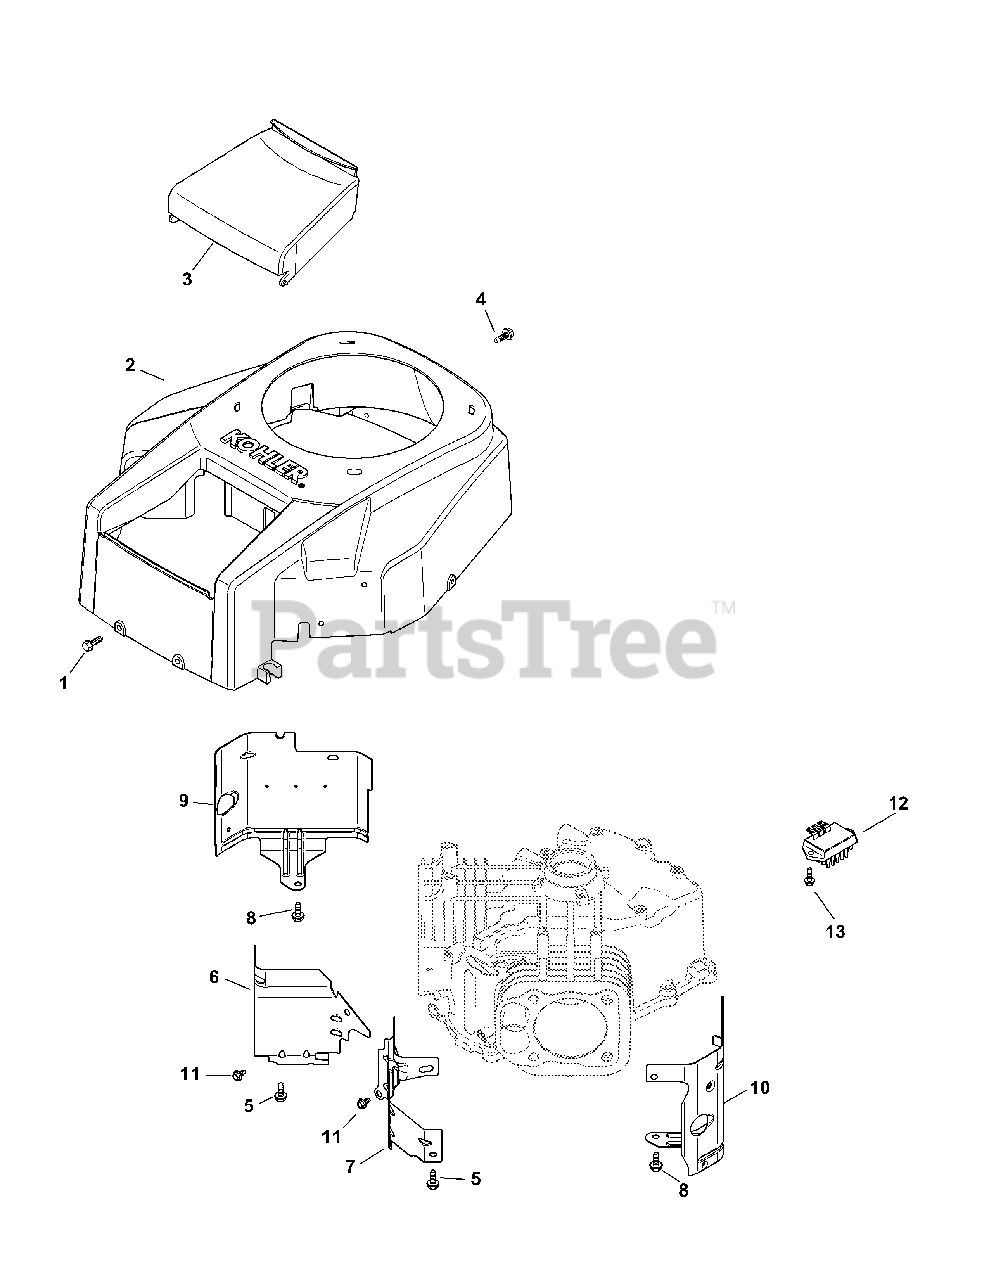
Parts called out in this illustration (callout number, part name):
1	Tap Screw, M6 x 1.7 x 18
2	Housing Blower Kit
3	Air Cleaner Cover
4	Flg. Thd. Frm. Screw, M5 x 0.8 x 16
5	Flg. Thd. Frm. Screw, M6 x 1.0 x 16
6	Valley Baffle - #1 Cylinder
7	Valley Baffle - #2 Cylinder
8	Flng. Thd. Frm. Screw, M6 x 1.0 x 10
9	Cyl Barrel Baffle - #1 Side
10	Cyl Barrel Baffle - #2 Side
11	Flg. Thd. Frm. Screw, M5 x .8 x 10
12	Regulator/Rectifier
13	Flg. Thd. Frm. Screw, M5 x .8 x 20
